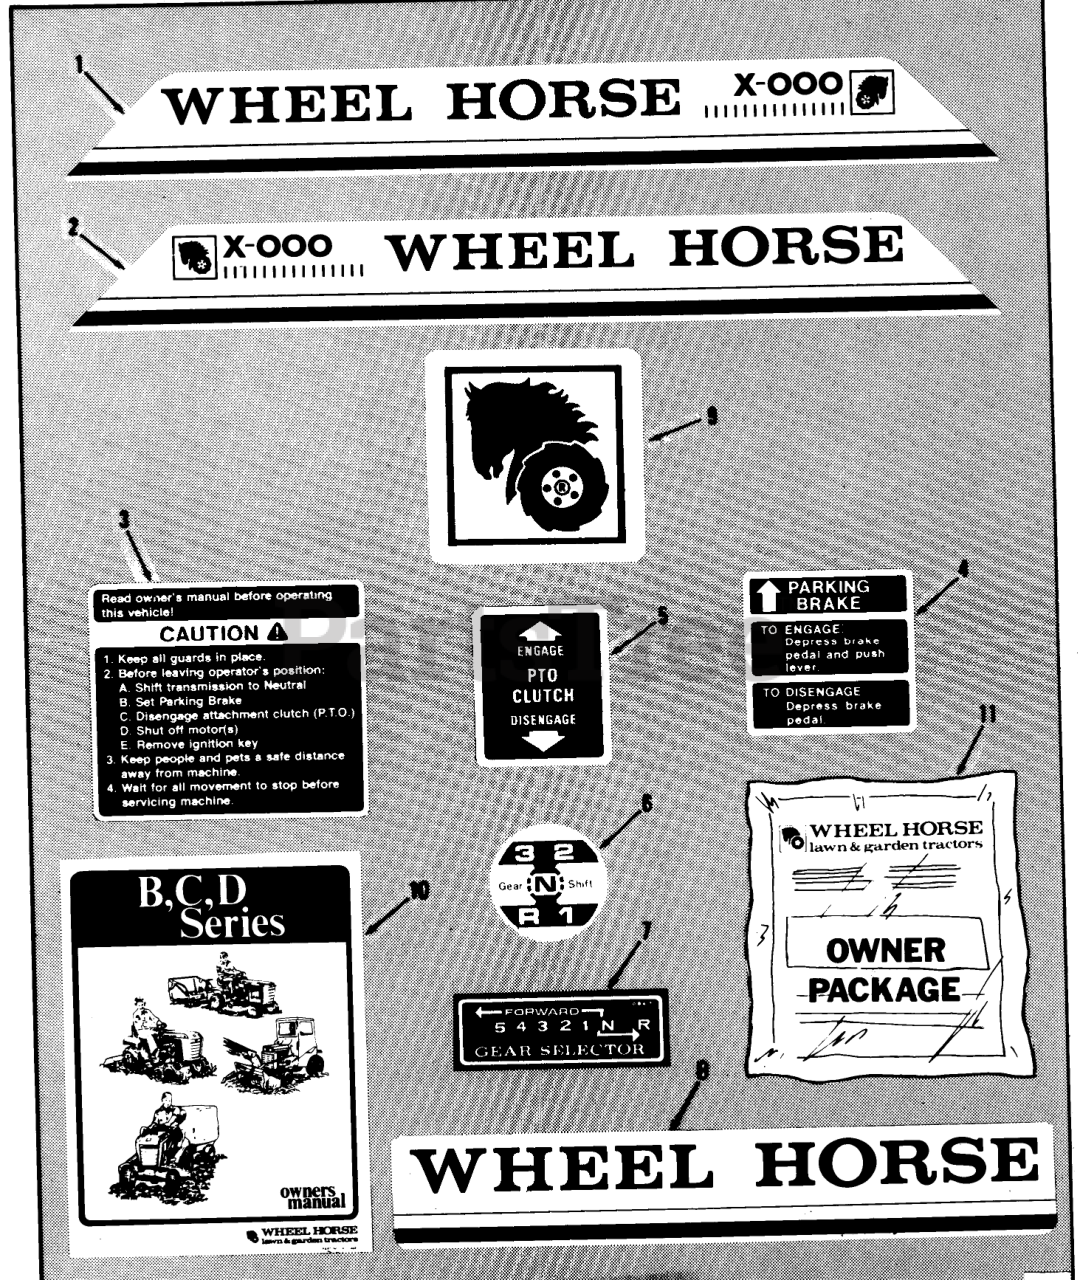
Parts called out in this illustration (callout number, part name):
1	Decal-Hood RH B-82
1	Decal-Hood RH B-112
1	Decal-Hood RH B-115
1	Decal-Hood RH B-165
2	Decal-Hood LH B-82
2	DECAL-HOOD B-112 LH
2	DECAL-HOOD B115 LH
2	Decal-Hood LH B-165
3	DECAL-CAUTION
4	Decal Parking Brake
5	DECAL-PTO CLUTCH
6	DECAL-SHIFT
7	DECAL-SHIFT
8	DECAL-REAR
9	DECAL-LOGO
10	Owner-s Manual
10	8-4321 Attachment Lift Instructions 02-11BP03, 02-16BP02 Only
10	Lift System Instructions 02-11 BP04, 02-16BP03 Only
11	New Tractor Loose Parts Package B-112 Only
11	New Tractor Loose Parts Package B-82 Only
11	New Tractor Loose Parts Package 02-11BP03 Only
11	New Tractor Loose Parts Package 02-11BP04 Only
11	New Tractor Loose Parts Package 02-16BP02 Only
11	New Tractor Loose Parts Package 02-16BP03 Only
